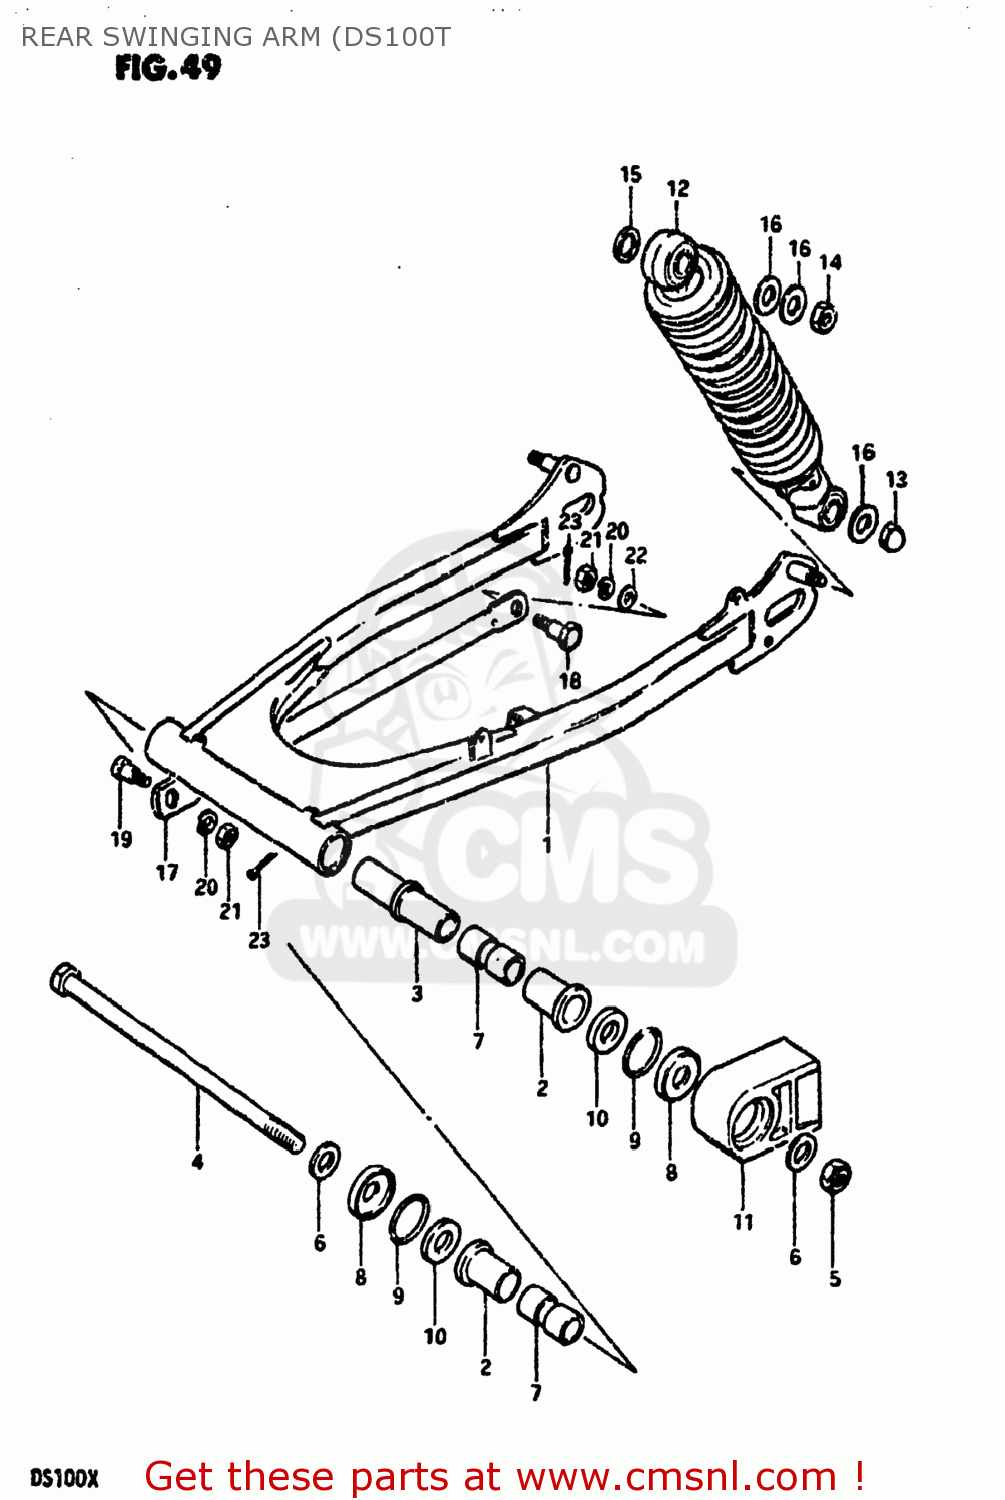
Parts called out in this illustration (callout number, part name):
1	SWING ARM ASSEMBLY,REAR
2	BUSH
3	SPACER,RR SWGARM PIVOT CTR
4	SHAFT,REAR SWING ARM
5	NUT 12MM
6	WASHER
7	SPACER,RR SWGARM PIVOT
8	COVER,SWGARM BUSH DUST SEAL
9	O RING(D:2,ID:24.5)
10	WASHER(12.5X24X2.3)
11	BUFFER,CHAIN TOUCH DEFLECTOR
12	ABSORBER ASSEMBLY,REAR SHOCK
13	NUT, LOWER LH
14	NUT
15	WASHER
16	WASHER
17	TORQUE LINK,REAR
18	BOLT(8X22)
19	BOLT(8X26.5)
20	LOCK WASHER
21	NUT
22	WASHER
23	PIN
